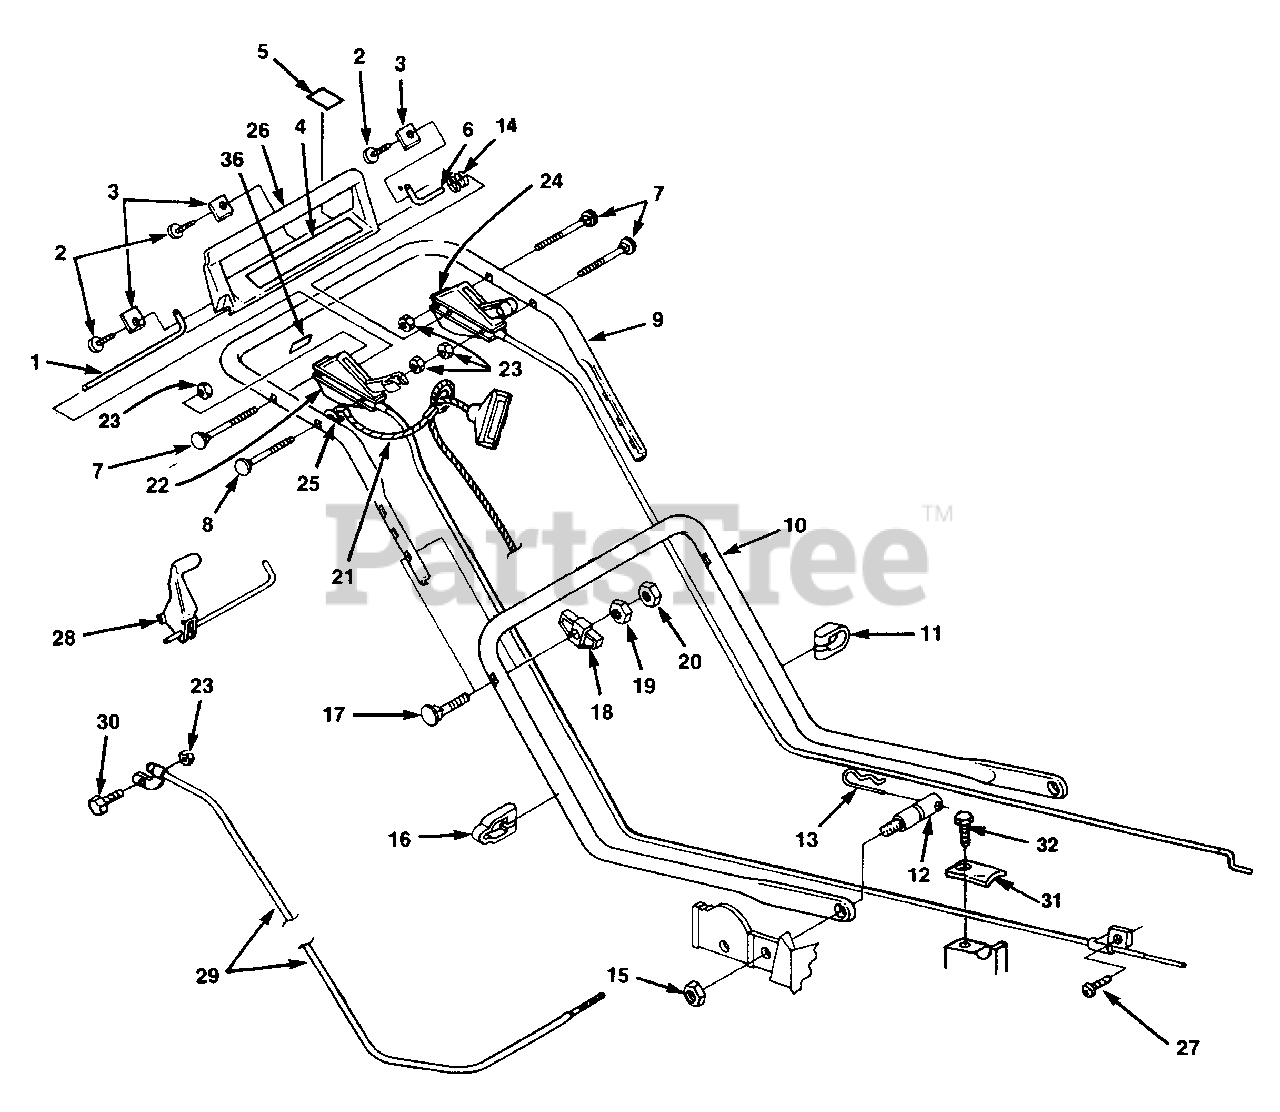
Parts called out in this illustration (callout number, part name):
1	SHAFT- Pivot
2	SCREW- 1/4-10 x 5/8
3	CLAMP- Pivot shaft
4	DECAL- Brake bail
5	DECAL- Blade rotation
6	SHAFT- Pivot (short)
7	BOLT- Sq. neck
8	BOLT- Sq. neck
9	HANDLE- Upper
10	HANDLE- Lower
11	CLAMP- Cable (single)
12	STUD- Handle mtg.
13	PIN- Cotter hair
14	SPRING- Compression
15	NUT- Hex. flange 5/16-18
16	CLAMP- Cable (double)
17	BOLT- Sq. neck
18	KNOB- Handle
19	NUT- Hex. 5/16 x 18
20	NUT- Hex.lock 5/16 x 18
21	ROPE- Restraint
22	CONTROL- Manual start
23	NUT- Hex locking 1/4-20
24	CONTROL- Throttle
25	WASHER- Curved
26	BAIL- Brake control
27	SCREW- Hex hd. 10-32 x 3/8
28	LEVER- Traction
29	CABLE- Traction
30	SCREW- Hex hd. 1/4-20 x 1 1/2
32	SCREW- Hex. hd. 1/4-20 x 5/8
